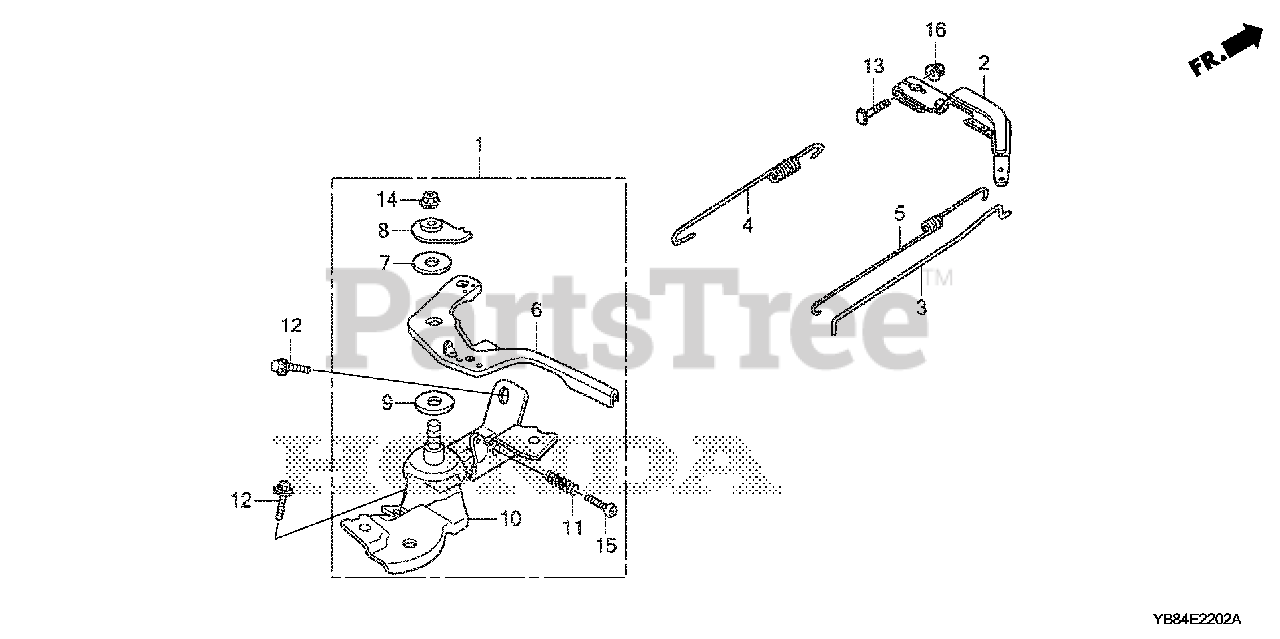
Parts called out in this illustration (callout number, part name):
1	CONTROL ASSY.
1	CONTROL ASSY. (COO)(FOR U.S.A.)
2	ARM, GOVERNOR
3	ROD, GOVERNOR
4	SPRING, GOVERNOR
5	SPRING, THROTTLE RETURN
6	LEVER, CONTROL
7	SPRING, LEVER
8	WASHER, CONTROL LEVER
9	SPACER, CONTROL LEVER
10	BASE, CONTROL
11	SPRING, CONTROL ADJUSTING
12	BOLT, FLANGE (6X12) (CT200)
13	BOLT, GOVERNOR ARM
14	NUT, SELF-LOCK (6MM)
15	SCREW, PAN (5X25)
16	NUT, FLANGE (6MM)
